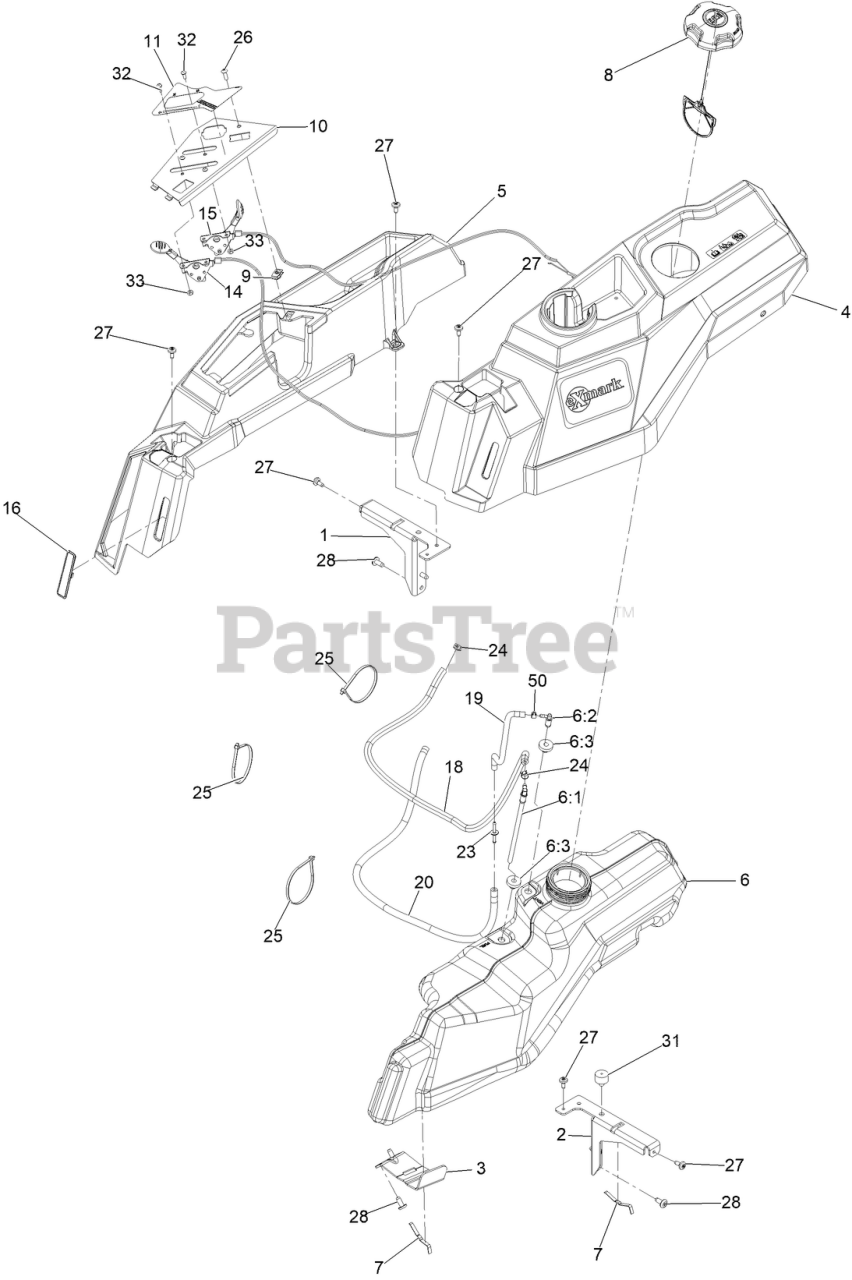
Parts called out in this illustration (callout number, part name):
1	SUPPORT-POD, RH
2	SUPPORT-POD, LH
3	SUPPORT-TANK, FUEL
4	POD- LH
5	POD- RH
6	TANK-FUEL ASM
6:1	Connector-Elbow, 90 DEG
6:2	Fitting-Elbow 90
6:3	BUSHING
7	SPRING
8	CAP-FUEL, RATCHETING
10	PANEL- CONTROL
11	DECAL-CONTROL PANEL
14	ASM,THROTTLE CABLE
15	CABLE-CONTROL, CHOKE
16	PLUG-SC
18	HOSE-FUEL
19	Hose-Fuel
20	Hose, Fuel
23	Adapter Orifice
24	CLAMP-HOSE
25	TIE-CABLE
26	SCREW-PRH
27	SCREW-SHOULDER
31	BUMPER-GROMMET
32	SCREW-PPH
33	NUT-LOCK, NI
50	CLAMP-HOSE
